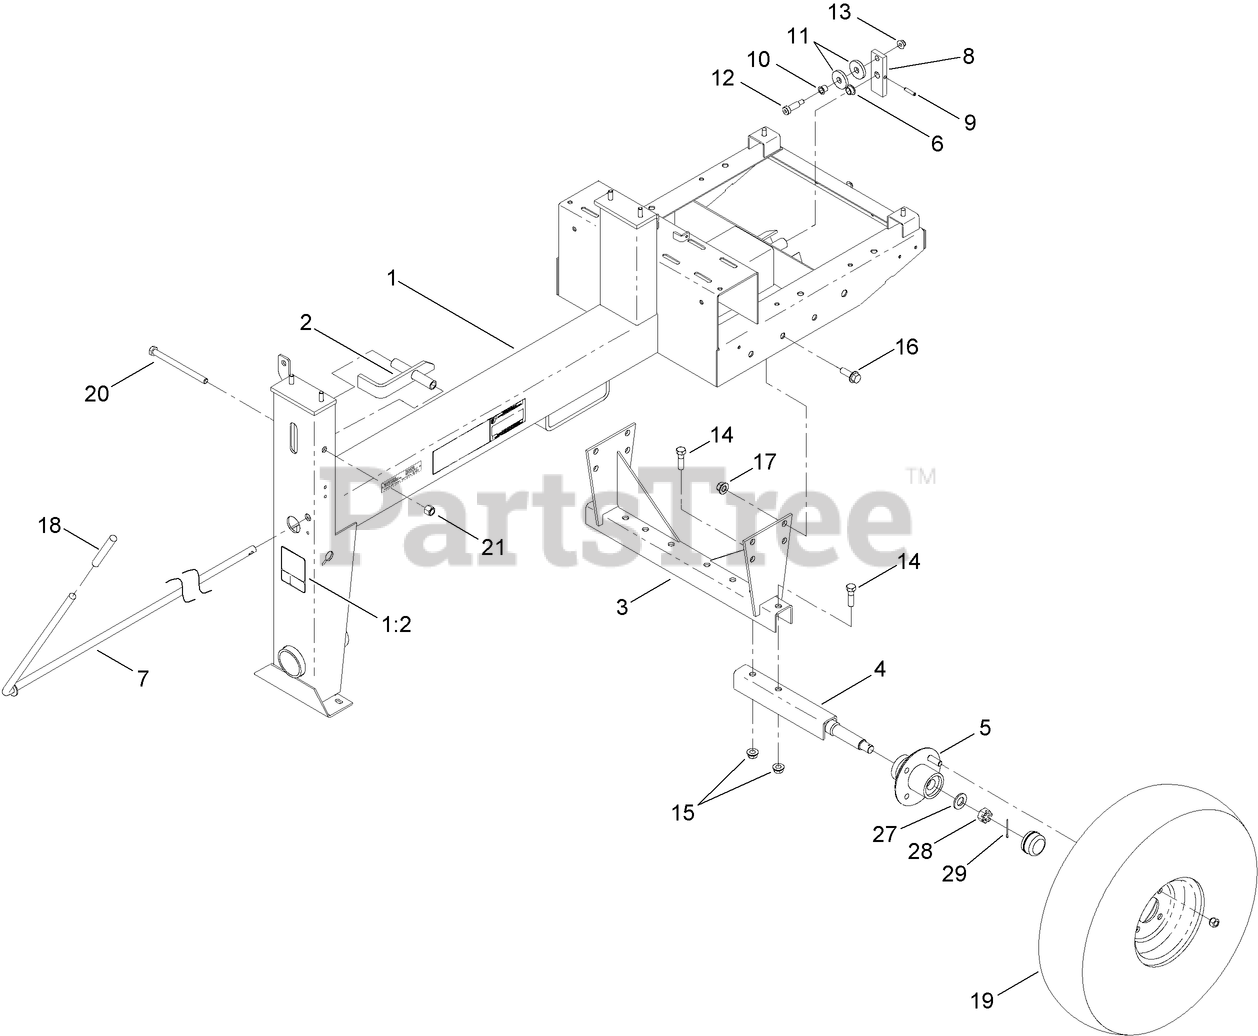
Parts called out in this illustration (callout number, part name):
1	FRAME ASM
1:2	DECAL-SAFETY CHAIN, TOWING
2	LATCH-DRUM
3	SUPPORT-AXLE
4	AXLE-HALF
5	HUB ASM
6	BUSHING-FLANGE
7	LEVER-CLUTCH
8	LINK-CLUTCH
9	PIN-SPRING
10	BUSHING-FLANGE
11	WASHER-FLAT
12	SCREW-HSBH
13	NUT-HF, NI
14	SCREW-HH
15	NUT-HHF
16	SCREW-HHF
17	NUT-LOCK
18	GRIP-HANDLE
19	TIRE AND RIM ASM
20	SCREW-HH
21	NUT-LOCK, NI
27	WASHER-FLAT
29	PIN-COTTER
